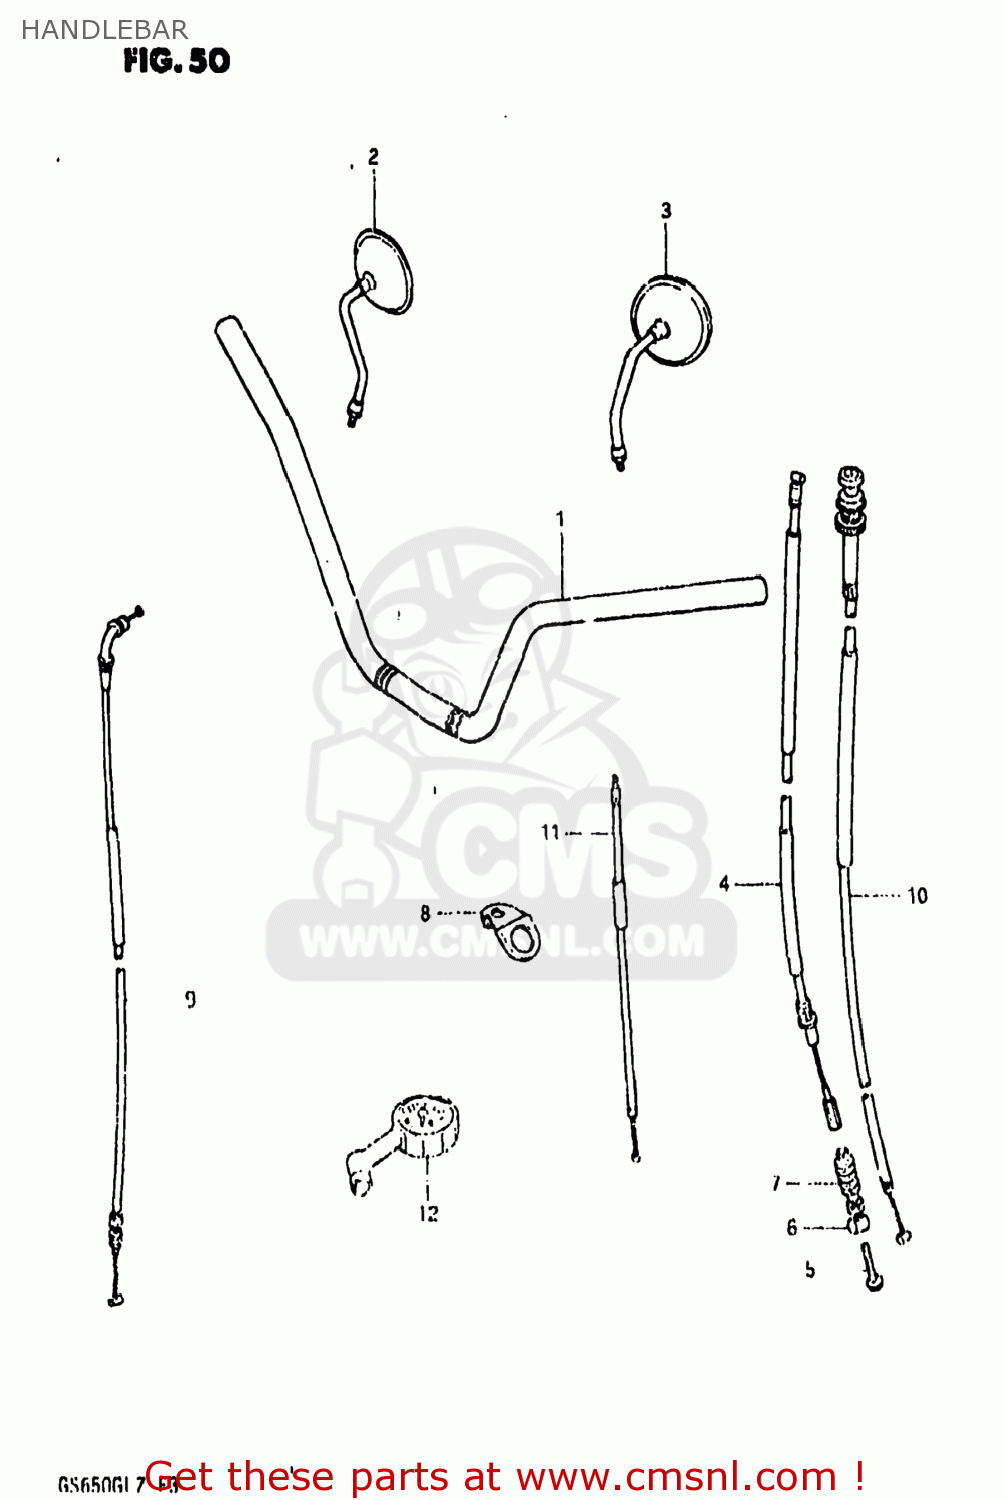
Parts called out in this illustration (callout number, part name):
1	HANDLEBAR
2	MIRROR ASSEMBLY,RIGHT
3	MIRROR ASSEMBLY,LEFT
4	CABLE ASSEMBLY,CLUTCH
5	SCREW
6	PIN
7	DUST SEAL
8	GUIDE,BRAKE HOSE
9	CABLE ASSEMBLY,THROTTLE
10	CABLE ASSEMBLY,STARTER
11	CABLE COMP,STARTER
12	GAUGE ASSY,AIR PRESSURE
